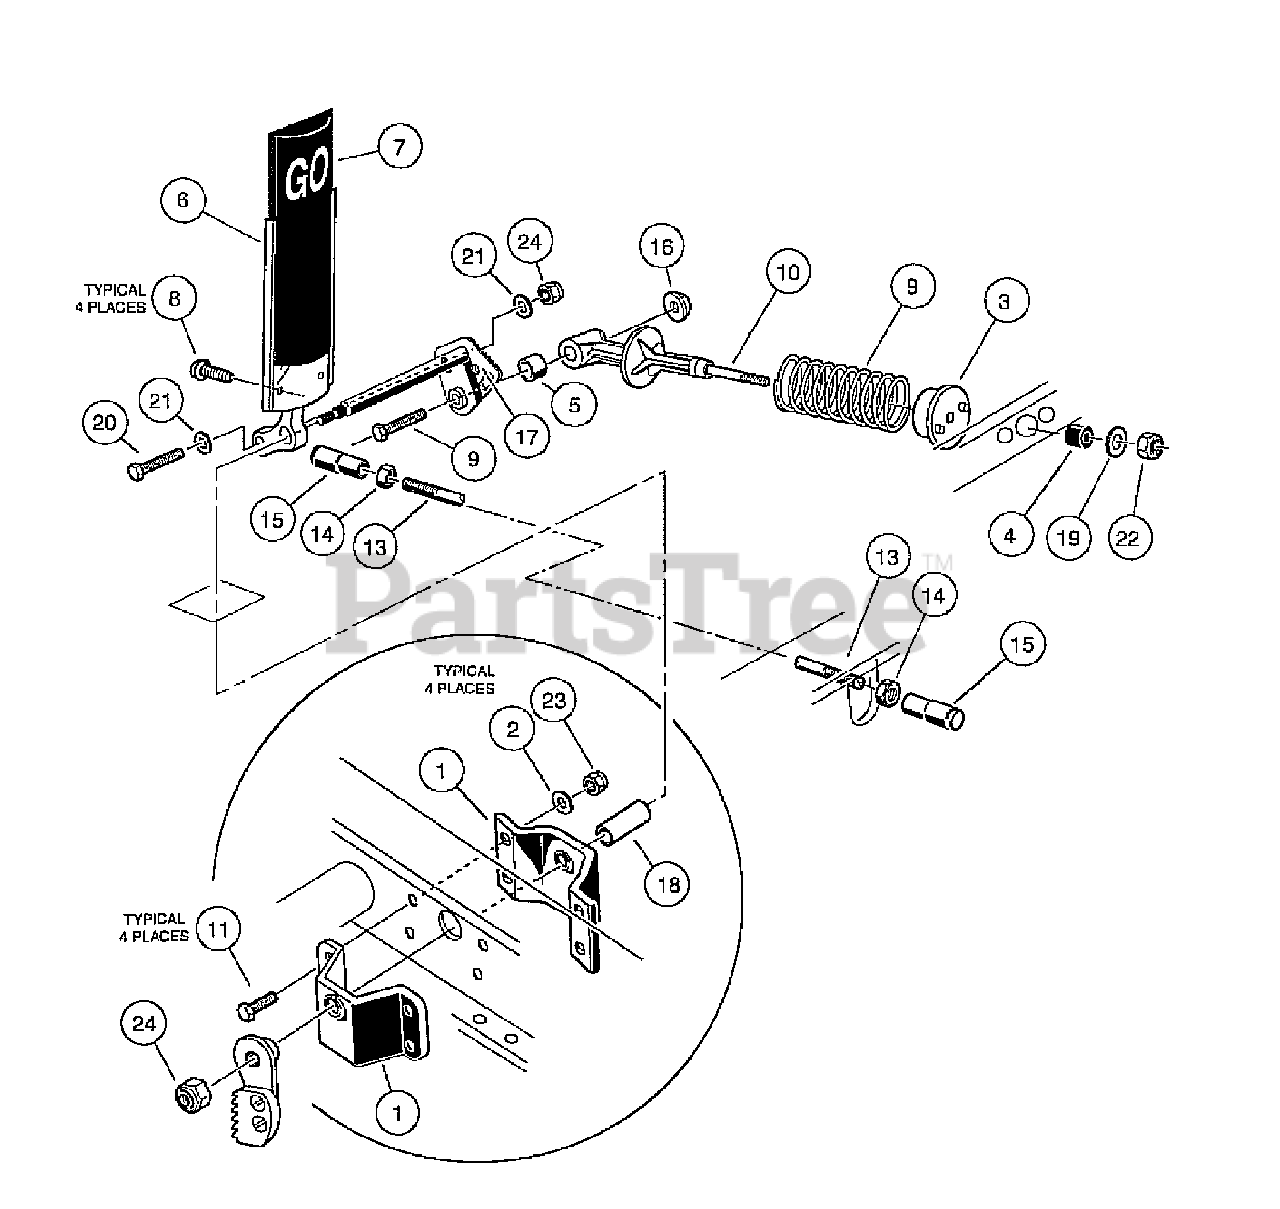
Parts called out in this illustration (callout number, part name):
1	Accelerator Bracket and Bearing Assembly
2	Washer, 1/4 Flat
3	Cup, Spring
4	Bumper, Spring Return
5	Bearing, Pivot Support
6	Sub Asm, Accelerator Pedal
7	Pad, Accelerator Pedal
8	Screw, #10-16 Type Ab Sht Mtl
9	Spring, Accelerator Return
10	Retainer, Spring
11	Screw, 1/4-20 X 1.125 Hex Cap
12	Screw, 1/4-20 X 1.500 Flange
13	Assembly, Accelerator Rod (gasoline vehicle)
14	Nut, 1/4-28 Hex Jam
15	Joint, Ball
16	Locknut, 1/4-28 Hex Flange Nyl
17	Kit, Accelerator Pivot Rod Assembly
18	Spacer, Accelerator
19	Washer, 5/16 Type A Flat
20	Screw, 3/8-16 X 1.50 Hx Hd Cap
21	Washer, 3/8 Type A Flat
22	Locknut, 5/16-18 Nylon Insert
23	Locknut, 1/4-20 Nylon Insert
24	Locknut, 3/8-16 Hex
